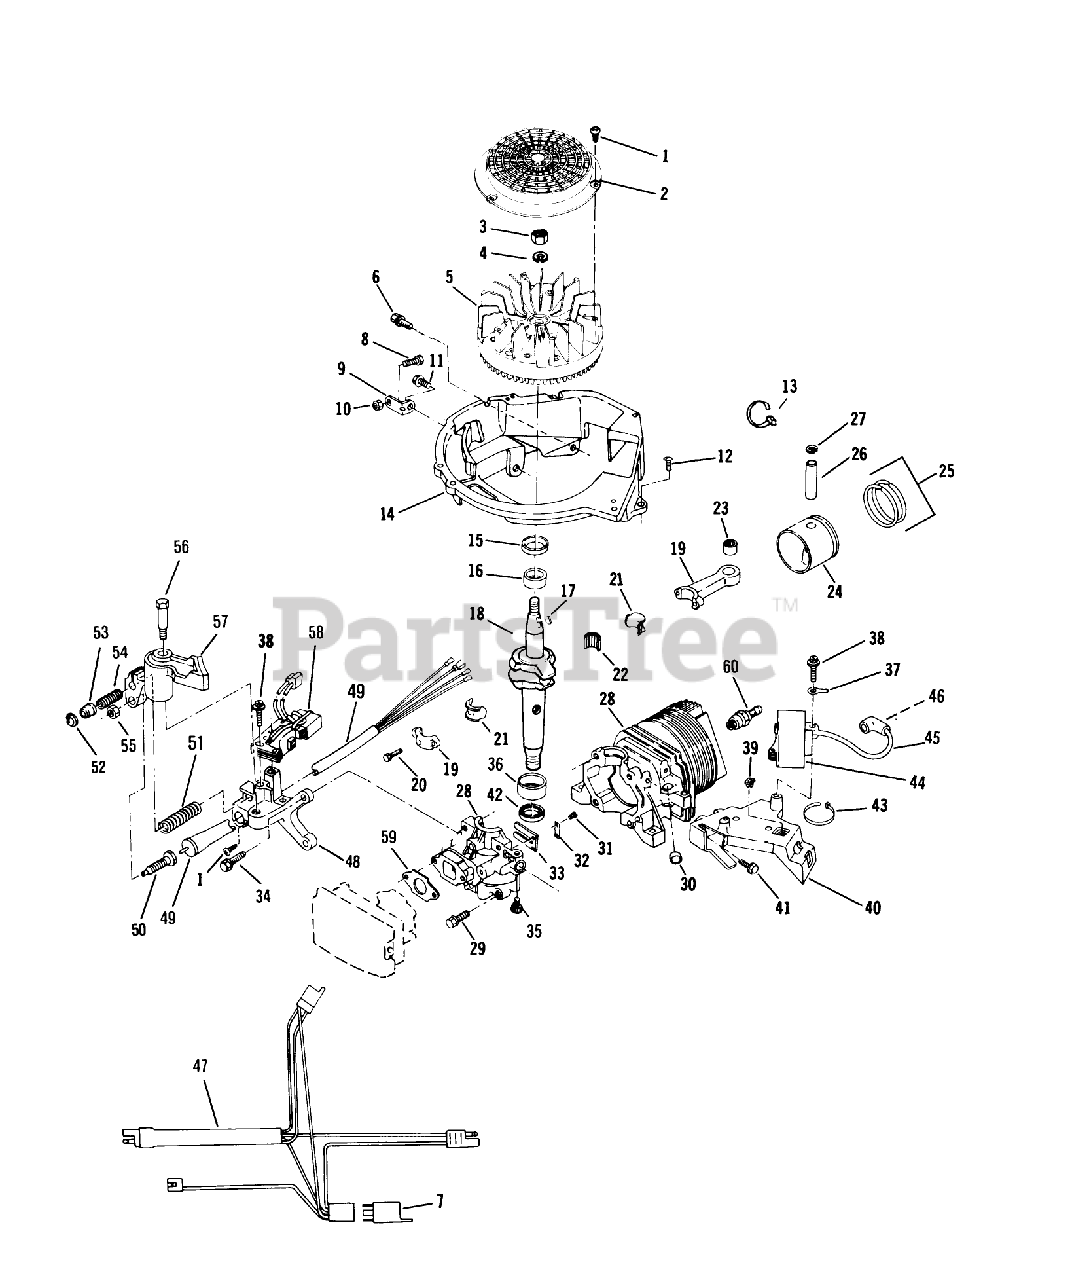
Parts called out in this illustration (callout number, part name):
1	SCREW F
3	NUT
5	FLYWHEEL ASSY F
6	SCREW-SEMS
8	BOLT F
10	NUT-LOCK F
12	SCREW F
14	BASE SHROUD F
15	SEAL-OIL
16	BEARING V
17	KEY
20	SCREW-HSH
21	LINER ASM
22	BEARING-NEEDLE
23	BEARING AY F
27	RING-RETAINING
29	SCREW S
30	PLUG-CORE VF
31	SCREW-HH
32	PLATE-BACKUP, REED
36	BEARING V
37	TERMINAL S
39	NUT-CLIP
40	BRACKET S
42	SEAL-OIL
45	HT LEAD&COVER XEV
48	BRACKET F
49	SWITCH AY.
50	PLUNGER S
51	SPRING-BRAKE
52	RETAINER S
53	ACTUATOR-LEVER, BRAKE
54	SPRING
55	Nut
59	GASKET CARB S
